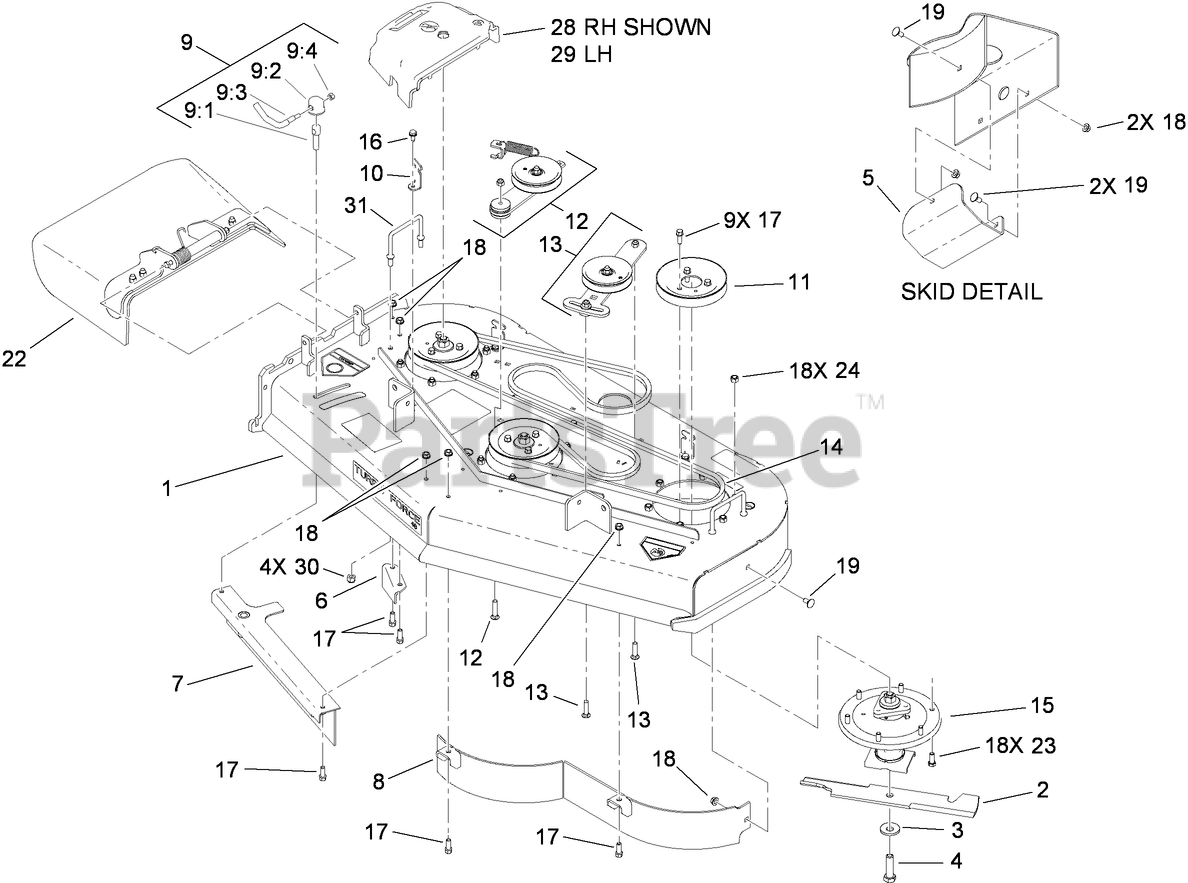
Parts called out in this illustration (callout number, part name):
1	DECK ASM
2	BLADE-16.5 INCH (HIGH FLOW)
3	Washer-Blade Bolt, Heavy
4	Screw-Cap
6	BAFFLE-DISCHARGE
8	48 INCH BAFFLE ASM
9	LEVER ASM
9:1	Screw-Lock
9:2	CAP-LOCK
9:3	Lever-Lock
9:4	NUT-LOCK, NI
10	BRACKET-COVER
11	PULLEY
12	SPRING IDLER ASM
13	IDLER ADJUST ASM
14	BELT-V
15	SPINDLE ASM
16	SCREW-HWHTF
17	SCREW-HWH
18	NUT-HHF, WHIZ
19	SCREW-CARR
22	DEFLECTOR ASM
23	SCREW-HH
24	NUT-LOCK, NI
28	COVER-BELT, RH
29	COVER-BELT, LH
30	NUT-LOCK, NI
31	WIREFORM-COVER
